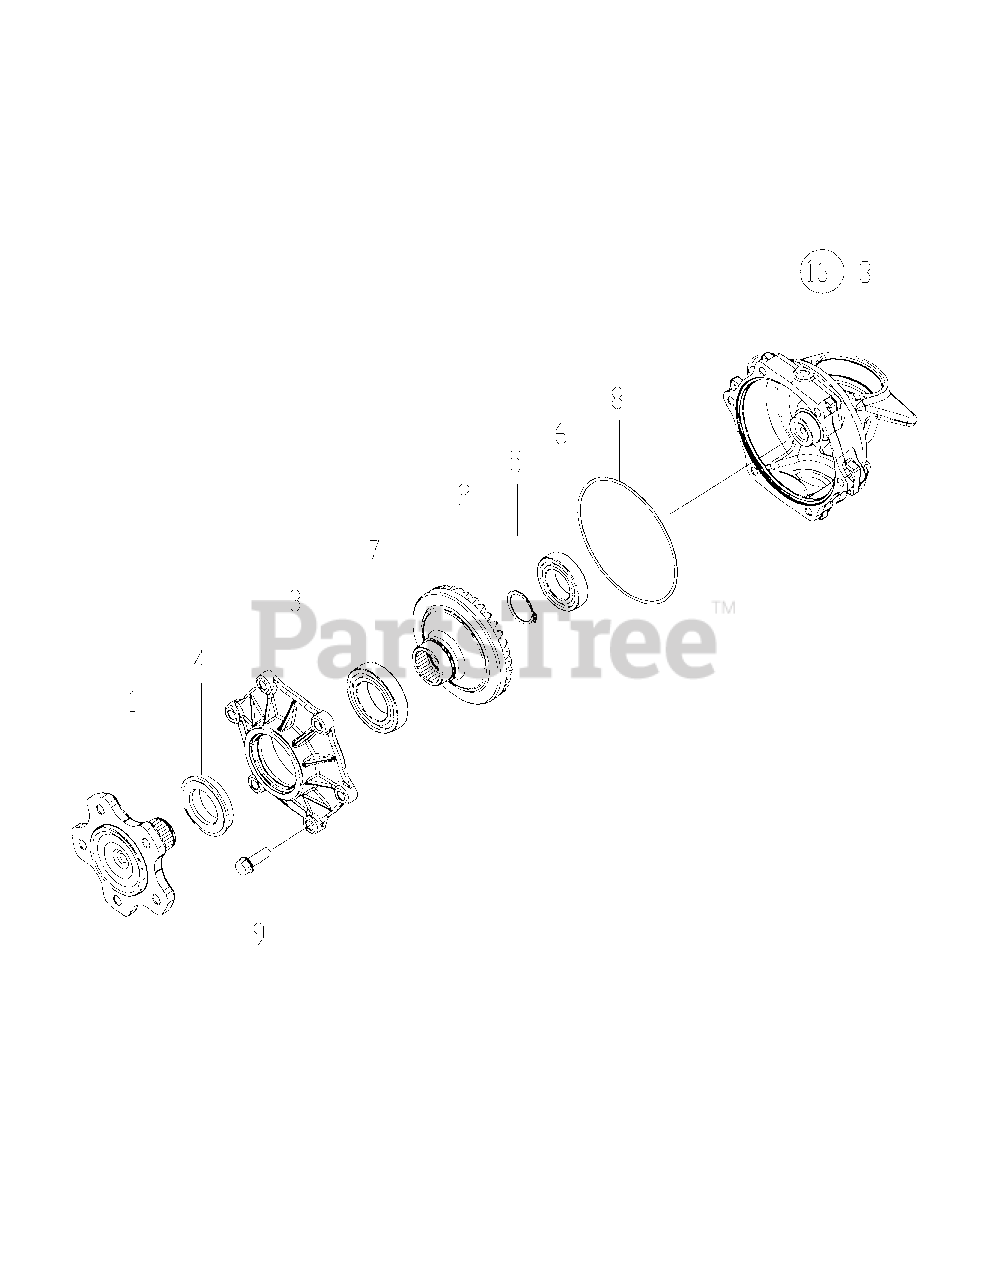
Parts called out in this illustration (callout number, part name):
1	SPINDLE, FRONT
3	CASE, FRONT BEARING
4	SEAL, QLFY40X62X14
6	BEARING, 6007 NTN
7	BEARING, 6009 NTN
8	PACKING,G130.0
